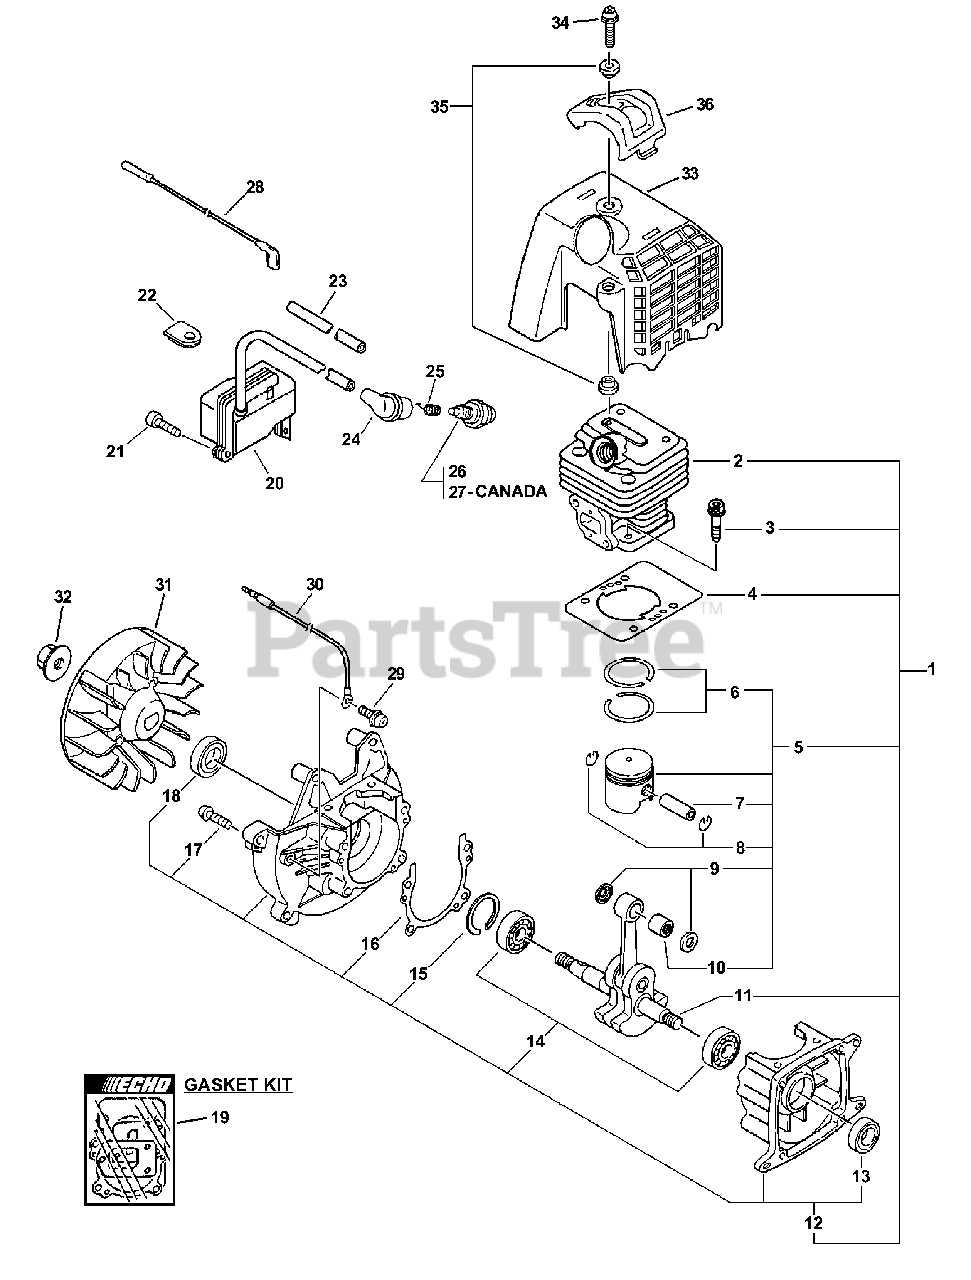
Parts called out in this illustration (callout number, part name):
1	SHORT BLOCK
2	CYLINDER
3	BOLT 5×22
4	GASKET, CYLINDER
5	PISTON KIT
6	RING, PISTON
7	PIN, PISTON 8
8	RING, SNAP
9	WASHER, THRUST
10	BEARING, NEEDLE 8
11	CRANKSHAFT ASSY
12	CRANKCASE KIT
13	SEAL, OIL 12
14	BEARING, BALL 6001
15	RING, SNAP 28
16	GASKET, CRANKCASE
17	BOLT 5×25
18	SEAL, OIL 12
19	GASKET KIT
20	COIL, IGNITION
21	BOLT 5×16
23	TUBE, INSULATOR
24	CAP, SPARK PLUG
25	TERMINAL, SPARK PLUG
26	SPARK PLUG - BPM8Y
27	SPARK PLUG - BPMR8Y
28	LEAD - IGNITION 145 MM
29	SCREW 5×10
30	LEAD - GROUND
31	FLYWHEEL
32	NUT, FLANGE M8
33	COVER, ENGINE - ORANGE
34	BOLT 5×16
35	COLLAR 5
36	GUARD, TOP
